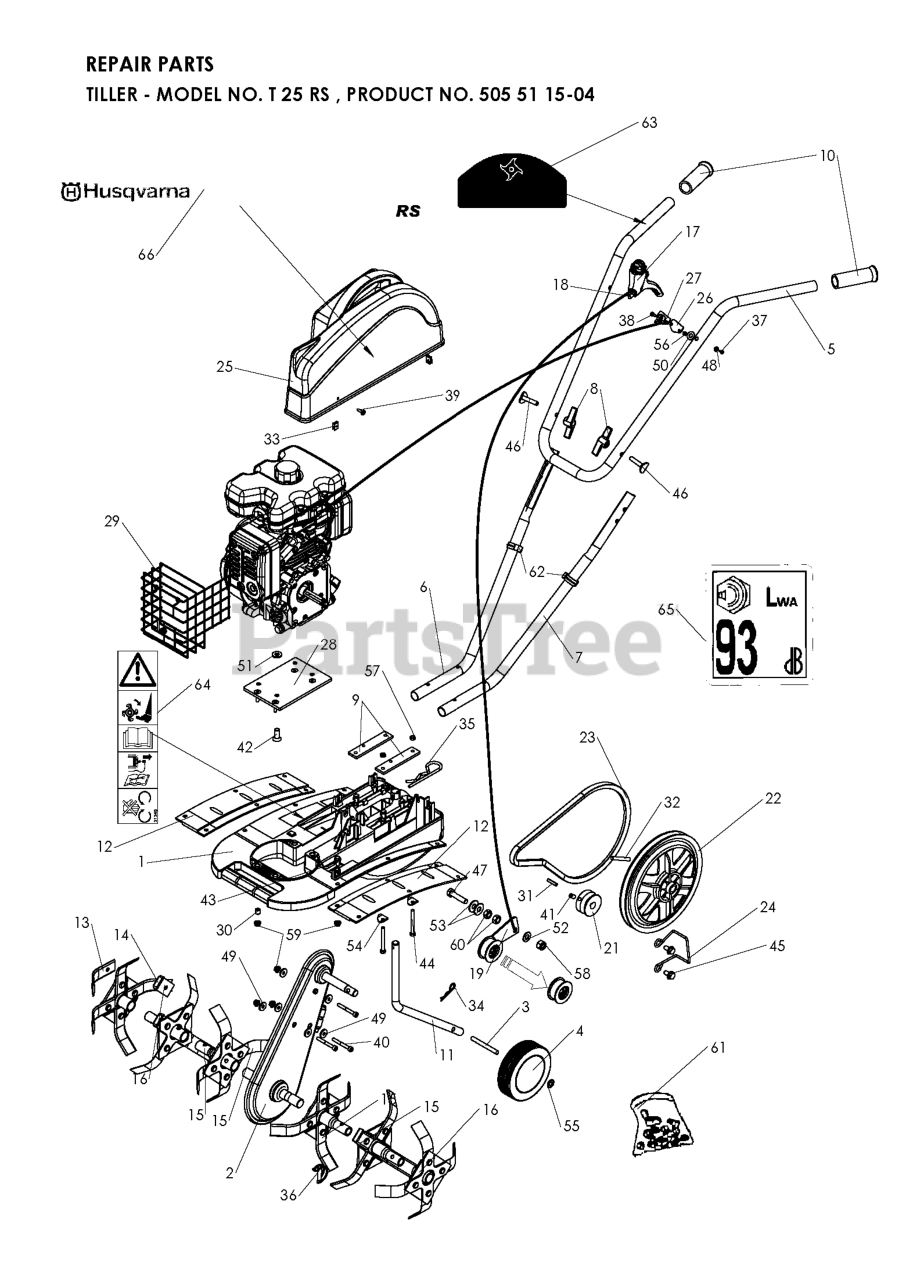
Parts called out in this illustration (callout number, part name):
18	CABLE CLUTCH
26	SUPPORT SWITCH
34	COTTER PIN
37	SCREW 0300080301
52	WASHER
57	Blocking nut M 6 Z
